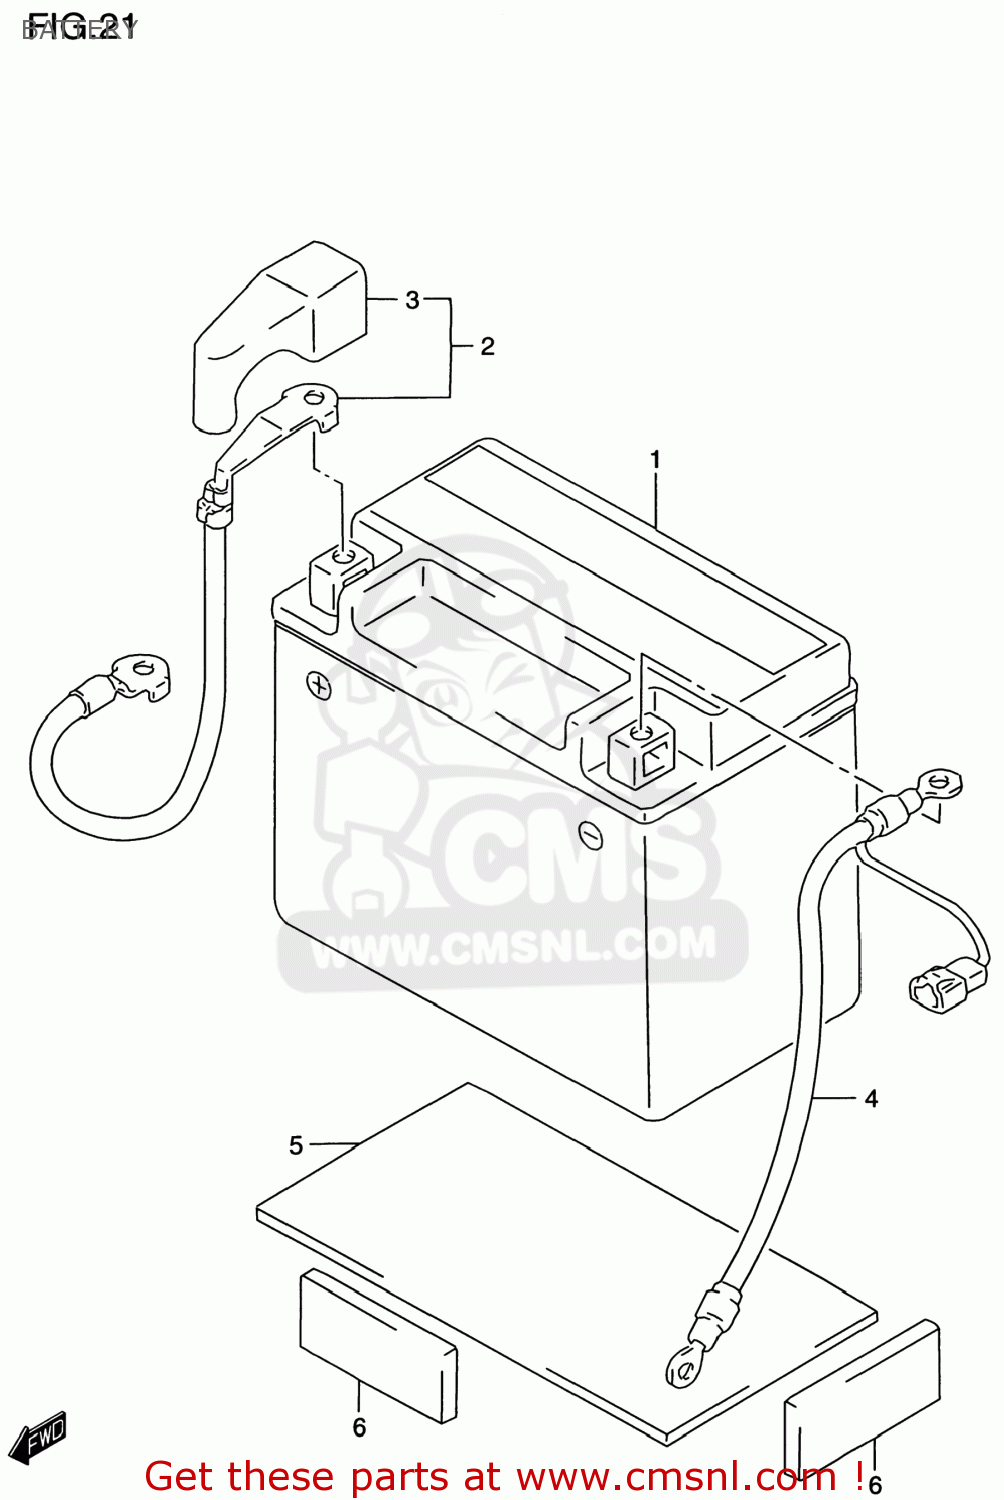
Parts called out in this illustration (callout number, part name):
1	BATTERY ASSY(YTX9-BS,12V8AH)
2	WIRE,BATTERY PLUS
3	CAP,BATTERY PLUS TERMINAL
4	WIRE,BATTERY MINUS
5	PROTECTOR(170X95X3.0)
6	CUSHION 20X45X6
